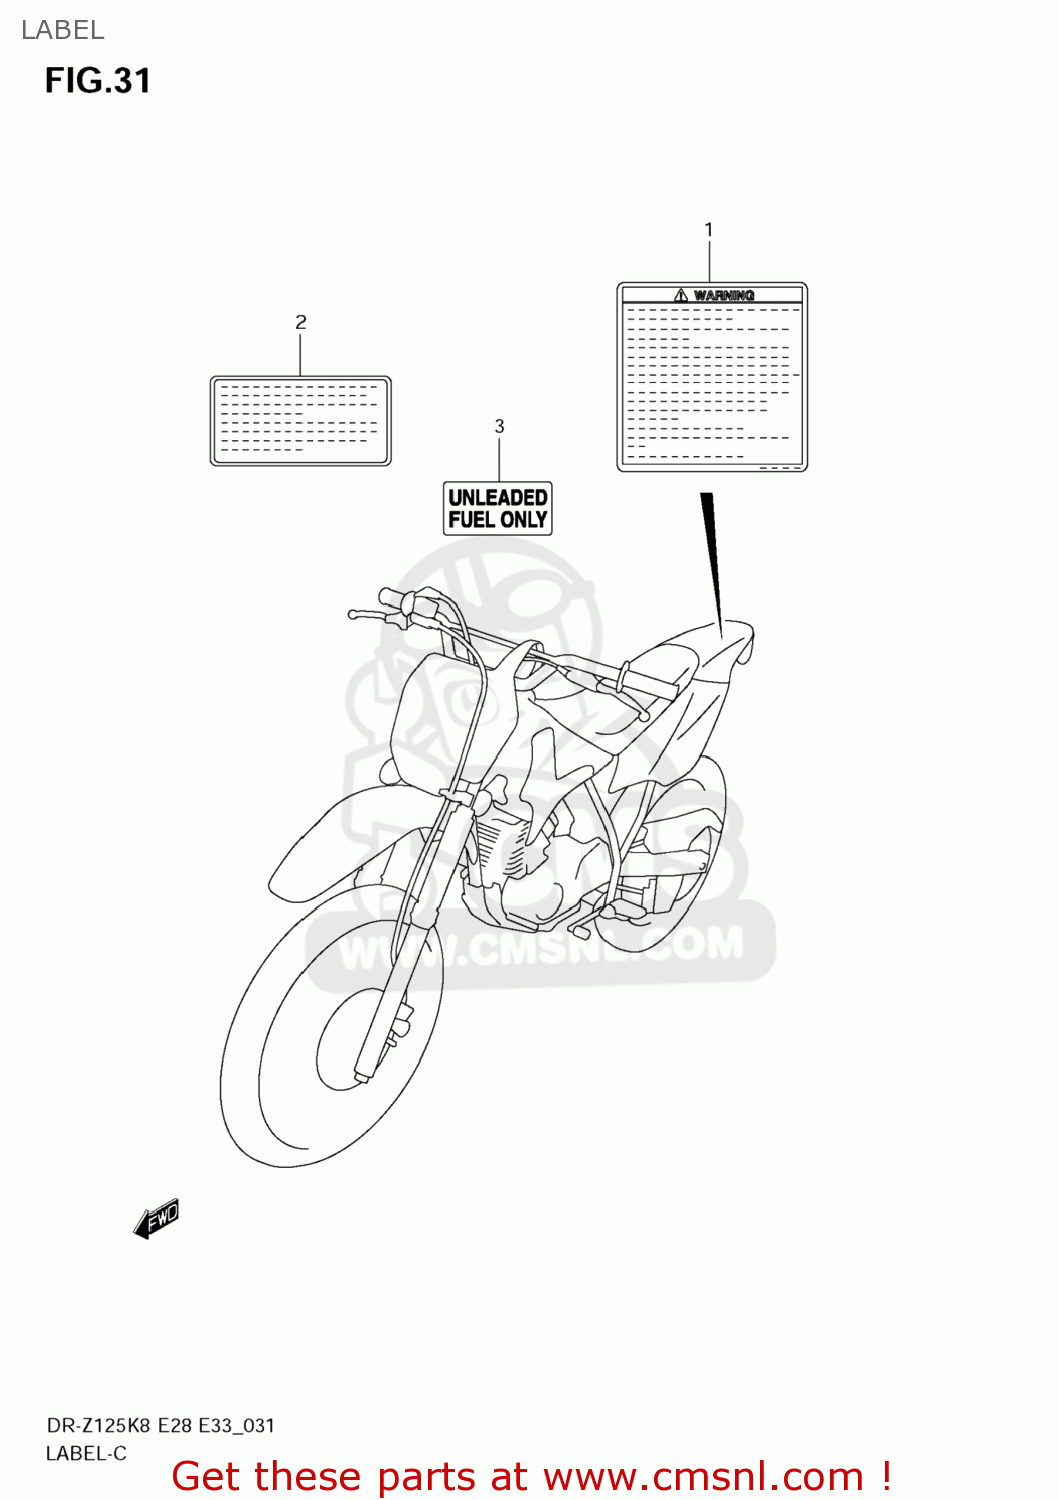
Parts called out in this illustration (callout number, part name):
1	LABEL,GENERAL WARNING
2	LABEL,MANUAL NOTICE
3	LABEL,UNLEADED FUEL
4	MANUAL,OWNER'S
